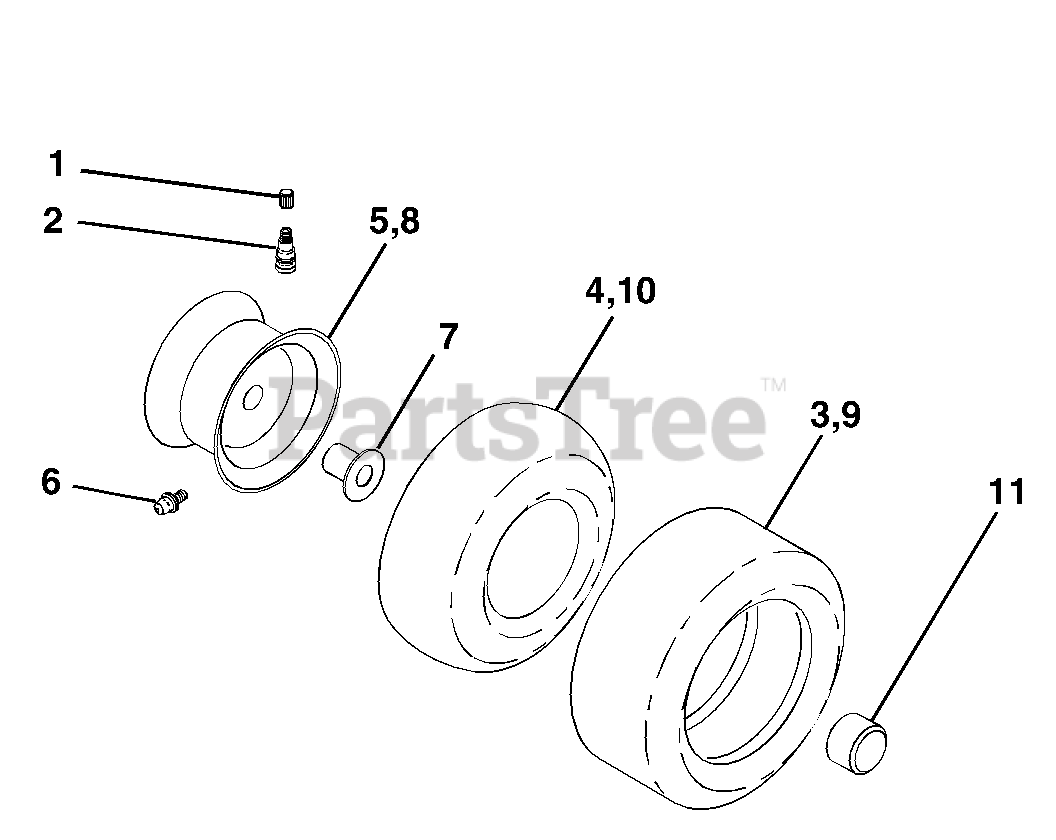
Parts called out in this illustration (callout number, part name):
1	Cap Valve Tire
2	Stem Valve
3	Tire F T 15 x 6 0 - 6
4	Tube Front
5	Rim Asm 6"front
6	Fitting Grease
7	Bearing Flange
8	Rim Asm 8"rear
9	Tire R T 20 x 10 -8 C
10	Tube Rear
11	Cap Axle 1 50 x 1 00
